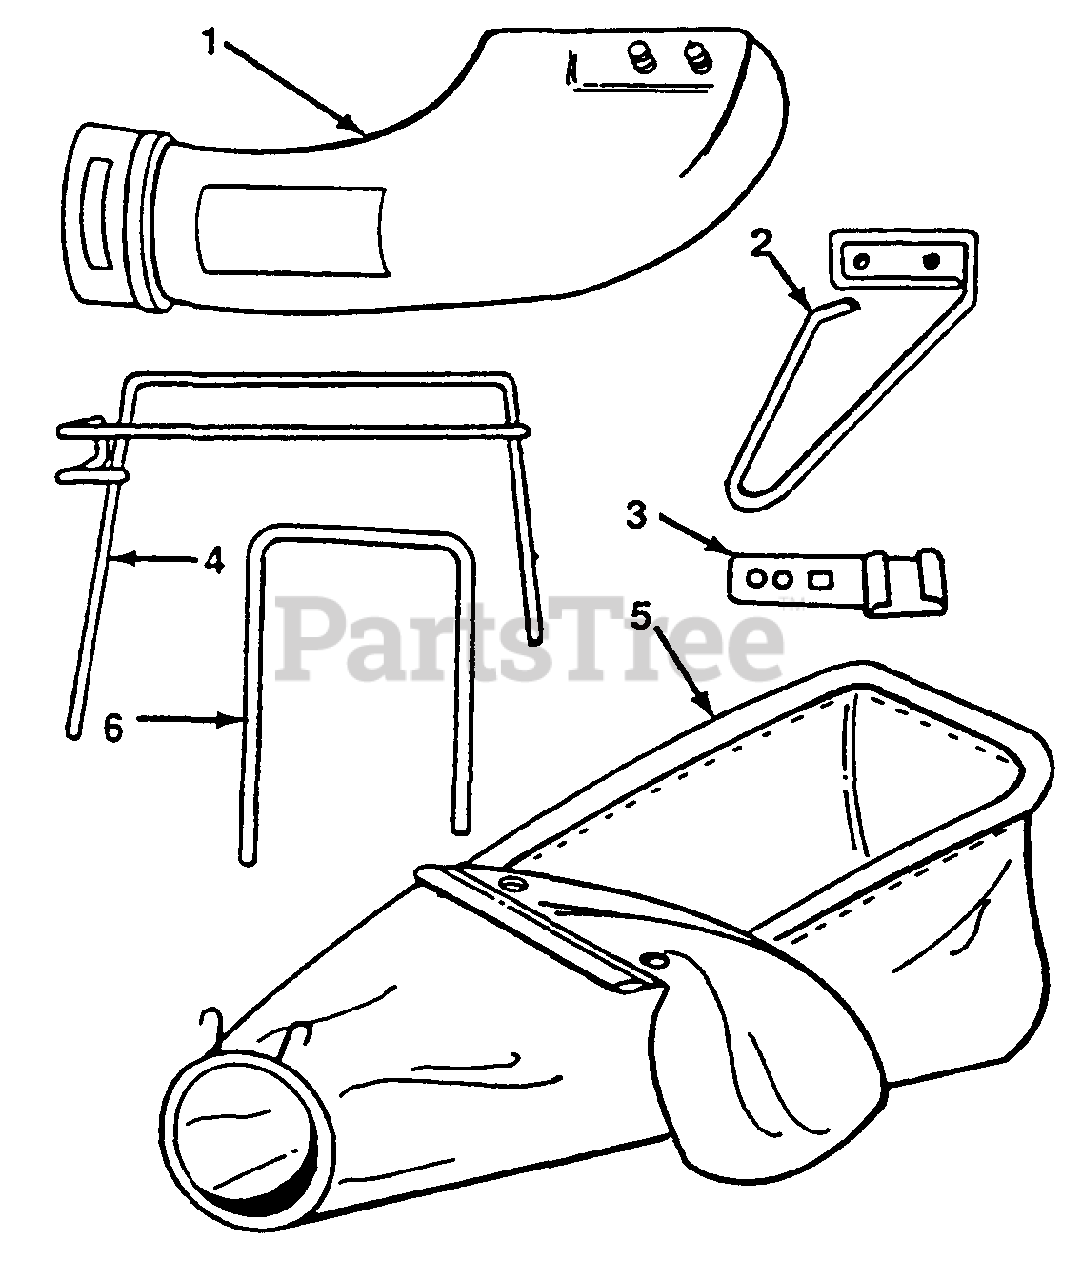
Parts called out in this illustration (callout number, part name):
1	Plastic Chute
2	Chute Mounting Bracket w/Wire
3	Handle Bracket
4	Bag Frame
5	Bag w/Clamp Ring
6	Upper Support Tube
